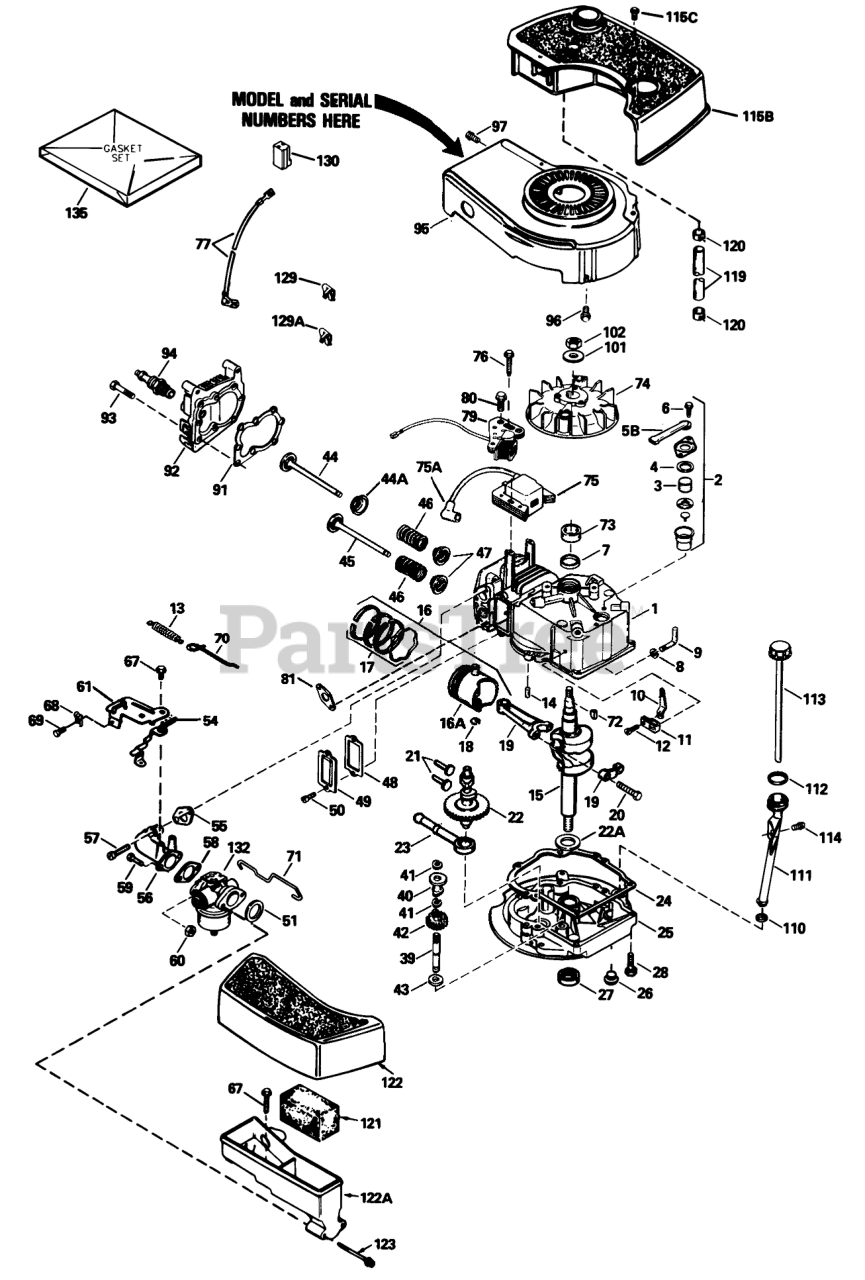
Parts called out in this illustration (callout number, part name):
1	Cylinder Assy. (Incl. Ref. #6 & 14)
2	Breather Assy. (Incl. Ref. #3-6 & 129)
3	Element-Breather
4	Gasket-Breather
5B	Tube, Breaker
6	Screw (10-24 x 9/16)
7	Seal-Oil
8	Washer-Flat
9	Rod, Governor (Incl. Ref. #8)
10	Governor Lever
11	Clamp-Lever, Governor
12	Screw
13	Spring Governor
14	Pin-Dowel
15	Crankshaft
16	Piston, Pin & Ring Assy. (STD.)(Incl. Ref. #16A, 17 & 18)
16	Piston, Pin & Ring Assy. (.010 oversize)(Incl. Ref. #16A, 17 & 18)
16	Piston, Pin & Ring Assy. (.020 oversize)(Incl. Ref. #16A, 17 & 18)
16A	Piston & Pin Assy. (Std.)(Incl. Ref. #18)
16A	Piston & Pin Assy. (.010 oversize)(Incl. Ref. #18)
16A	Piston & Pin Assy. (.020 oversize)(Incl. Ref. #18)
17	Ring Set-Piston (Std.)
17	Ring Set, Piston(.0100versize)
17	Ring Set (.020" OS)
18	Ring-Retaining, Piston Pin
19	Rod Assy., Connecting (Incl. Ref. #20)
20	Bolt-Rod, Connecting
21	Lifter-Valve
22	Camshaft(Mech.Comp. Release)
22A	Washer-Thrust
23	Oil Pump ASM
24	Gasket
25	Flange, Mounting (Incl. Ref. #26, 27 & 39)
26	Plug Oil Drain
27	Seal-Oil
28	Screw (1/4-20 x 1-1/4)
39	Shaft-Governor
40	Spool-Governor
41	Ring-Retaining
42	Gear Assy., Governor (Incl. Ref. #43)
43	Washer
44	Valve, Intake (Std.) (Incl. Ref. #47)
44	Valve, Intake (1/32" oversize) (Incl. Ref. #47)
44A	Seal Assy., Intake
45	Valve, Exhaust (Std.) (Incl. Ref. #47)
45	Valve, Exhaust (1/32" oversize) (Incl. Ref. #47)
46	Spring-Valve
47	Cap-Valve, Spring
48	Gasket-Cover, Valve
49	Cover-Valve
51	Gasket-Air Cleaner
54	Lever Control
55	Gasket-Intake Pipe
56	Pipe, Intake (Incl. Ref. #55)
57	Screw (1/4-20 x 1)
58	Gasket-Carburetor
59	Screw (1/4-28 x 7/8)
60	Nut and Lock Washer (1/4-28)
61	Bracket Assy., Control (Incl. Ref. #54 & 67)
67	Screw, Hex Washer Hd Shoulder Self-Tap
68	Conduit
69	Screw (10-32 x 3/8)
70	Link Governor Spring
71	Link-Throttle
72	Key-Flywheel
74	Flywheel
75	Solid State
75A	Cover-Spark Plug
76	Screw
77	Wire-Ground
79	Coil, Alternator
80	Screw (8-32x27/64)
81	Gasket, Exhaust
91	Gasket-Cylinder Head
92	Head-Cylinder
93	Screw (5/16-18x1-1/2)
94	Spark Plug-Resistor (R J19 L M)
95	Housing-Blower
96	Screw (1/4-20x19/32)
97	Screw (10-24 x 9/16)
101	Washer-Belleville
102	Nut-Flywheel
111	Tube, Oil Fill
113	Dipstick, Oil
114	Screw (10-32 x 1/2)
115B	Tank Assy. (Incl. Ref. #118 & 120)
115C	Screw (10-32 x 35/64)
119	Line-Fuel
120	Clamp-Line, Fuel
121	Filer, Air
122	Cove, Air Cleaner
122A	Body Air Cleaner
123	Screw Fil Hd.
129	Clip-Wire
129A	Clip, Breather
130	Connector-Body
132	Carburetor (Incl. Ref. #58)
135	Gasket Set (Incl. items marked )
